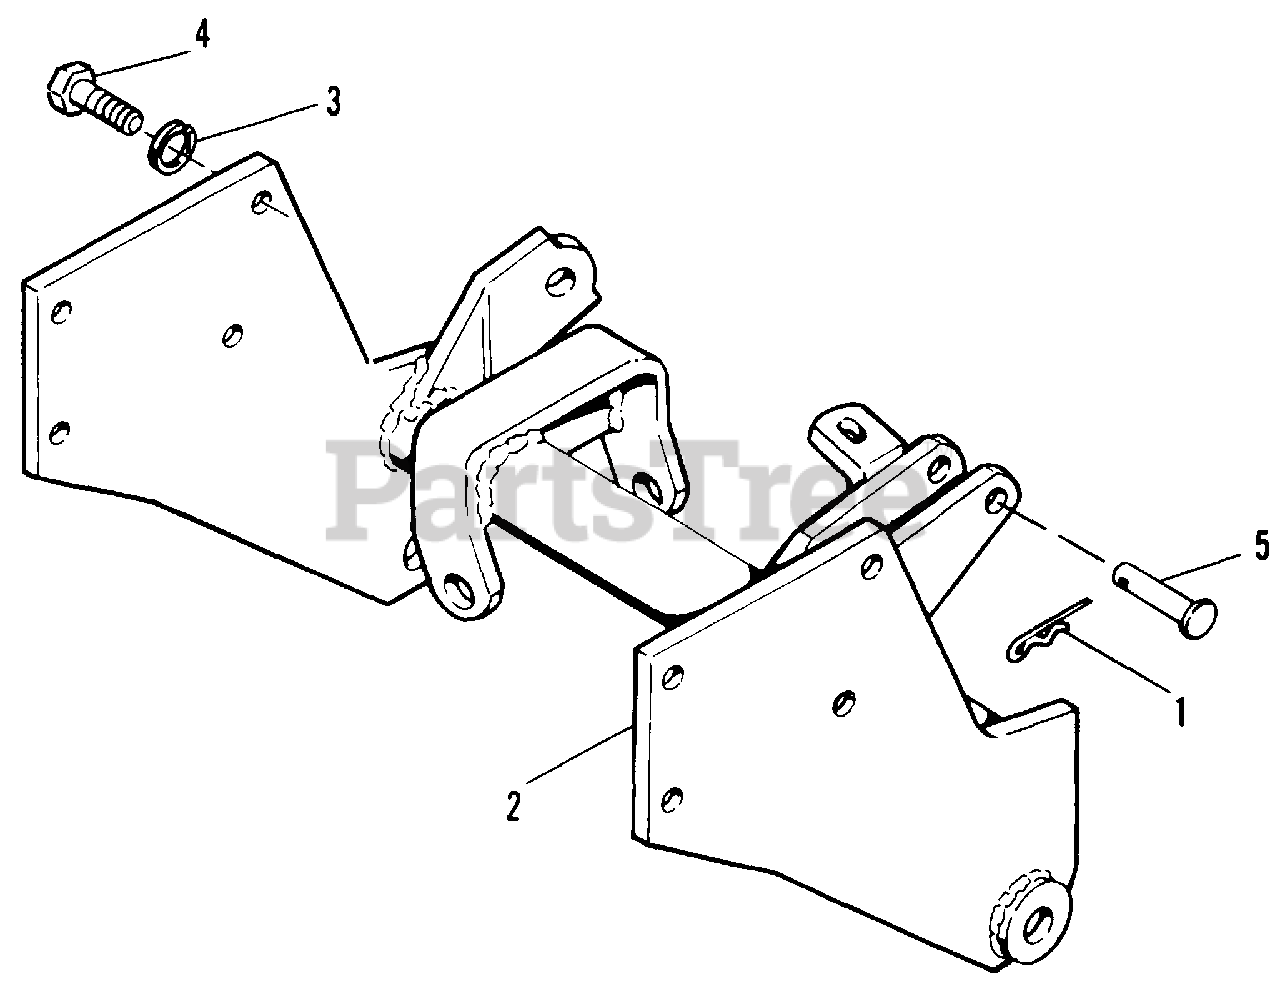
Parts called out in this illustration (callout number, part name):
1	CLIP, Spring
2	SUPPORT ASSY, Hitch
3	LOCKWASHER, Spring, 1/2
4	CAPSCREW, Hex Hd., 1/2-13 x 1-1/4
